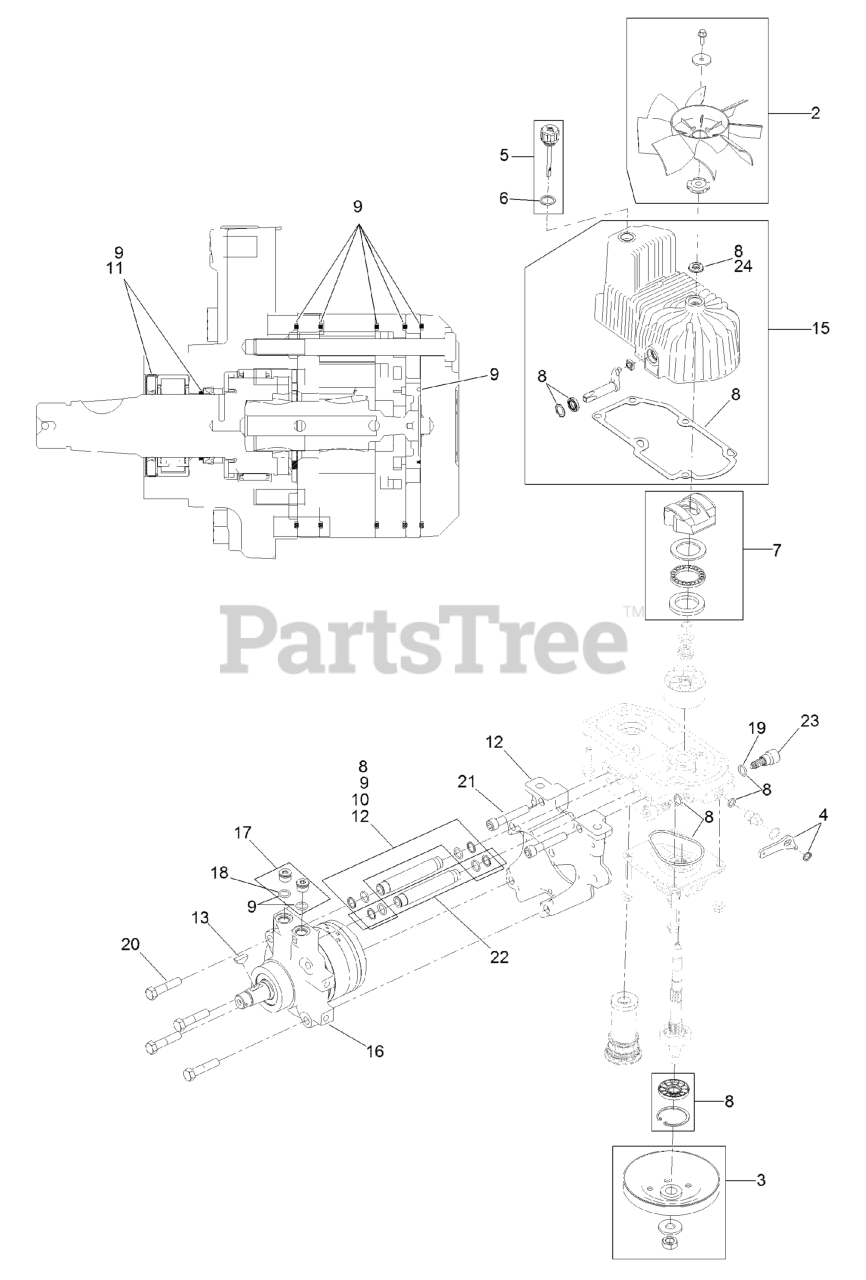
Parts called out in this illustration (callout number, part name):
2	FAN KIT
3	PULLEY KIT
4	HANDLE-BYPASS VALVE, HYDRO
5	DIPSTICK-HYDRO W/GASKET
6	GASKET-DIPSTICK, HYDRO
7	SWASH BLOCK KIT
8	PUMP SEAL KIT
9	MOTOR SEAL KIT
10	TUBE SEAL KIT
11	OUTPUT SHAFT SEAL KIT
12	NOSE CUP-UHT
13	KEY-WOODRUFF
15	HOUSING-HYDRO, LH
16	MOTOR-HYDRAULIC, LH 280CC
17	MAGNETIC PLUGS SERVICE KIT
19	O-RING-CHECK VALVE
20	SCREW HH
21	SCREW-HSH
22	HYDRAULIC TUBE KIT
23	SHOCK VALVE, 16CC HYDRO
24	SEAL-FAN DRIVE
25	16Cc LH Pump Section Kit
26	16Cc LH Rotating Grp Kit
